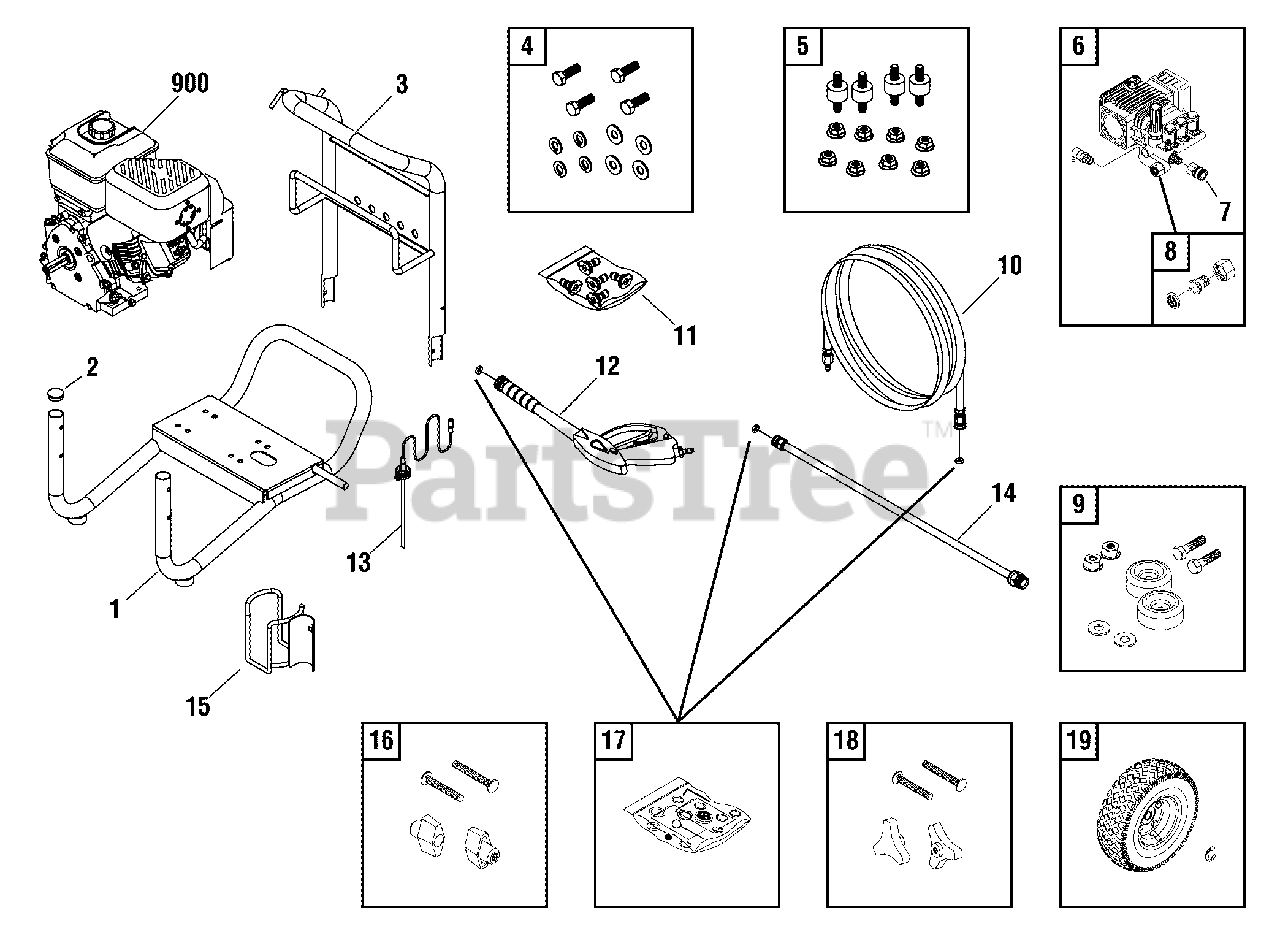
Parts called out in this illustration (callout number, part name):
4	KIT-HARDWARE PUMP MOUNTING
5	KIT-VIBRATION MOUNT
7	ADAPTER
8	ADAPTER-GARDEN HOSE
9	MOUNT-VIBRATION
12	GUN
14	EXTENSION-QC
16	KIT-HARDWARE HANDLE
17	O-RINGS
18	KIT-HARDWARE HANDLE
